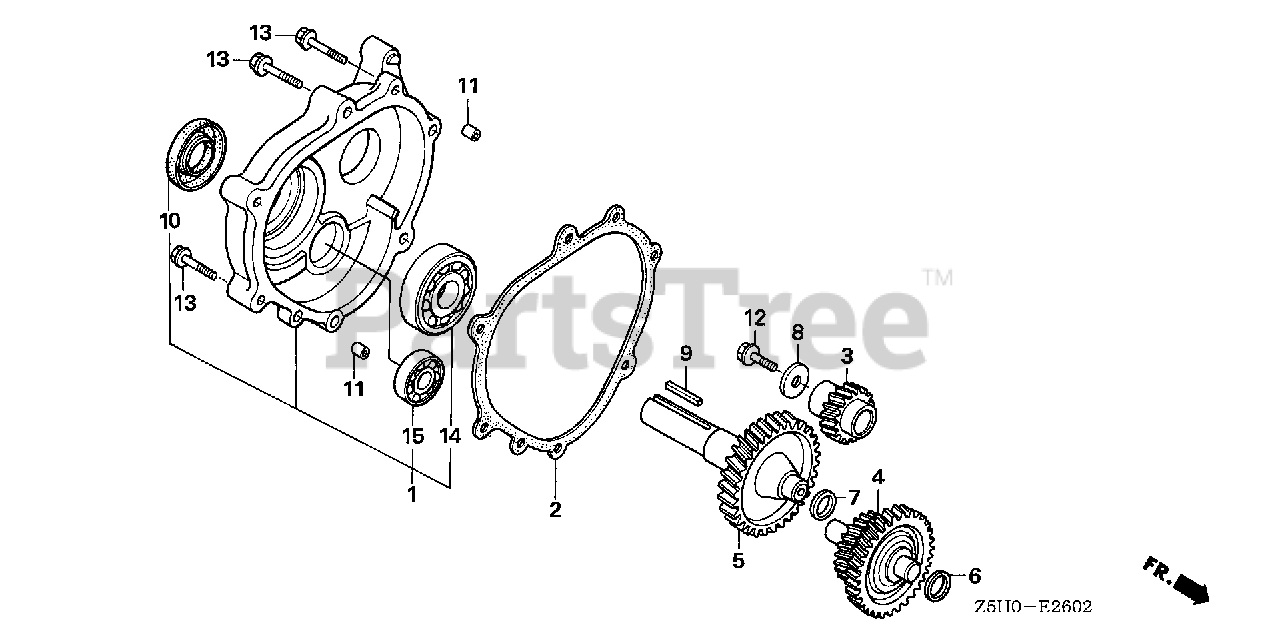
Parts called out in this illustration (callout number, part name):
1	COVER ASSY., REDUCTION CASE
2	GASKET, CHAIN CASE COVER
3	GEAR, PRIMARY DRIVE (17T)
4	COUNTERSHAFT (18T/40T)
5	SHAFT, P.T.O. (46T)
8	WASHER (8MM)
9	KEY (6.3X6.3X43)
10	OIL SEAL (30X46X8)
11	PIN, DOWEL (8X14)
12	BOLT, FLANGE (8X25)
13	BOLT, FLANGE (8X40)
14	BEARING, RADIAL BALL (6206)
15	BEARING, RADIAL BALL (6302)
